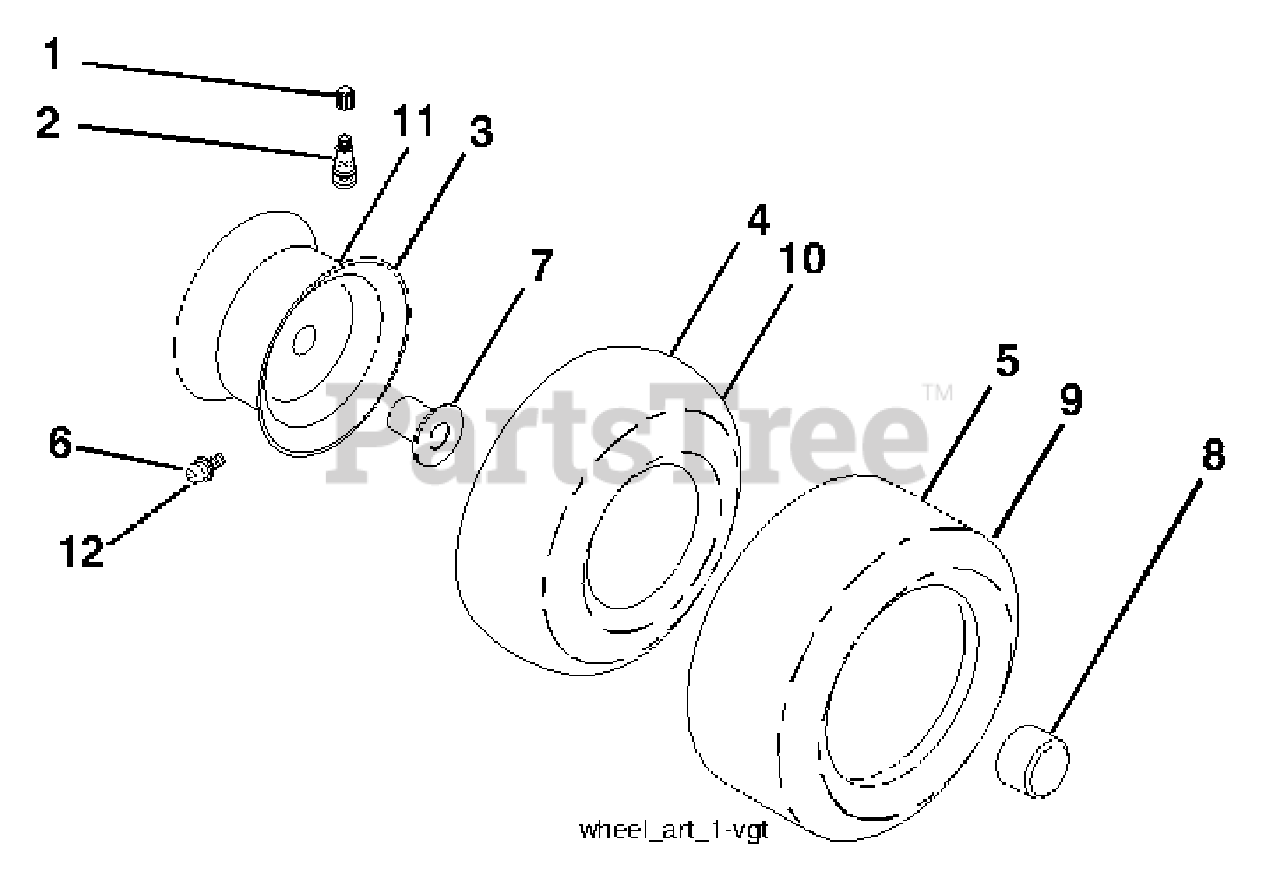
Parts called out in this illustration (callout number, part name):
1	Cap, Valve, Tire
2	Stem, Valve
3	Rim Assembly, Front
4	Tube, Front (Service Item Only)
5	Tire, Front
6	Fitting, Grease
7	Bearing, Flange (Front Wheel Only)
8	Cap, Hub
9	Tire, Rear
10	Tube, Rear (Service Item Only)
11	Rim Assembly, Rear
12	Fitting, Grease
